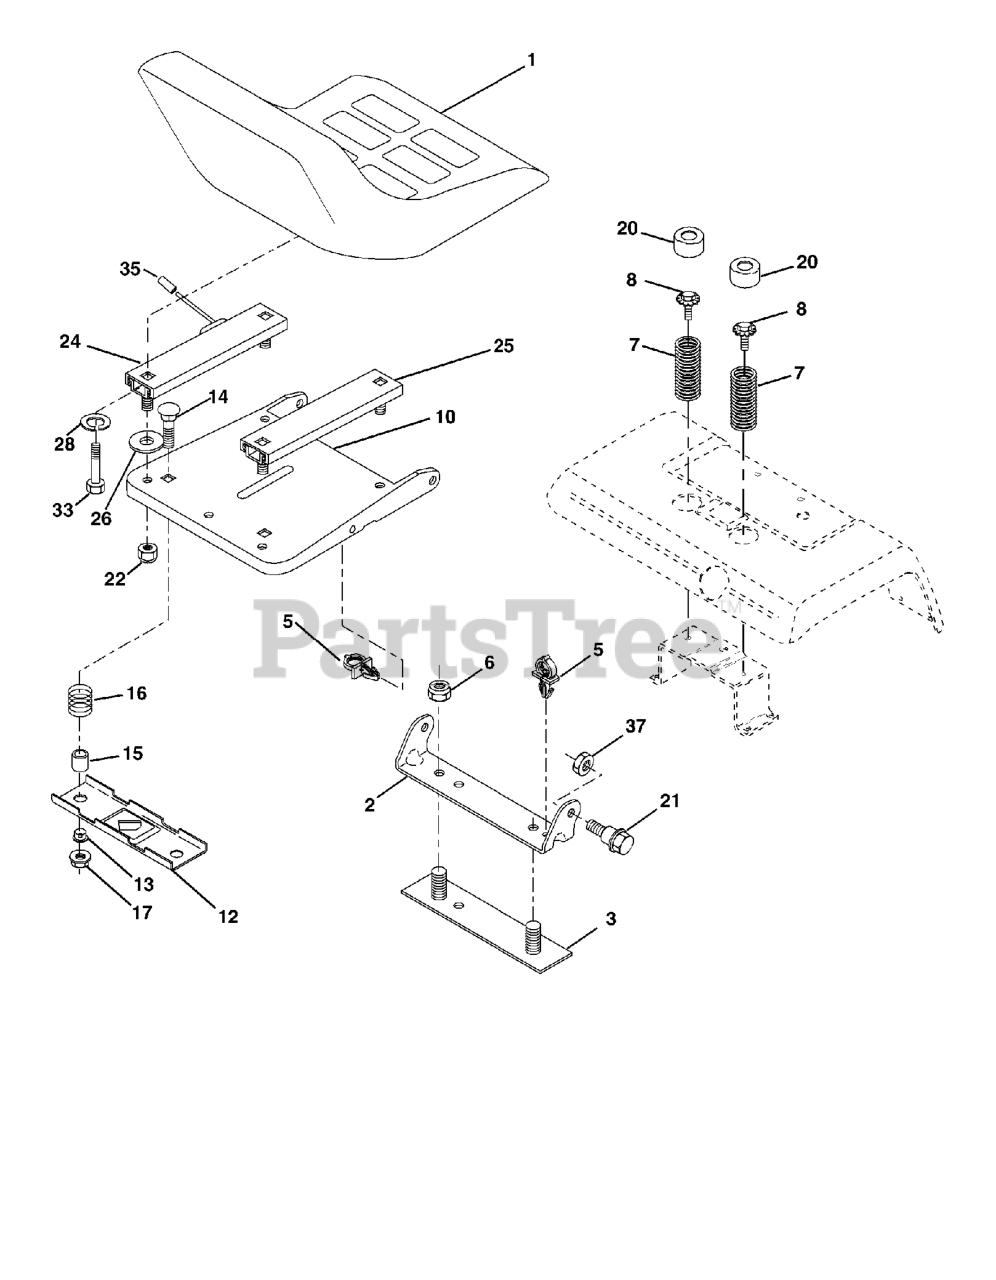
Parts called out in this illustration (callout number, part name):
1	SEAT.XH150.GRY
2	SEAT PIVOT BRKT
3	STRAP
5	PUSH CLIP
6	NUT
7	SPRING COMPRESSION
8	BOLT.5/16-18UNCX3/4 W/SEMS.BLK
10	PAN SEAT
12	BRKT SWITCH
13	BUSHING
14	BOLT.ROUND.HEAD.SQUARE.NECK
15	SPACER SPLIT
16	SPRING COMPRESSED
17	NUT T
20	CAP SPRING
21	BOLT.SHOULDER.5/16-18
22	LOCKNUT
24	TRACK SLIDE, SEAT(L)
25	TRACK SLIDE, SEAT(R)
26	WASHER T
28	WASHER
33	BOLT.FIN.HEX.5/16-18X3/4
35	CAP
37	NUT.71038.31-18.HEX.NYLOCK
